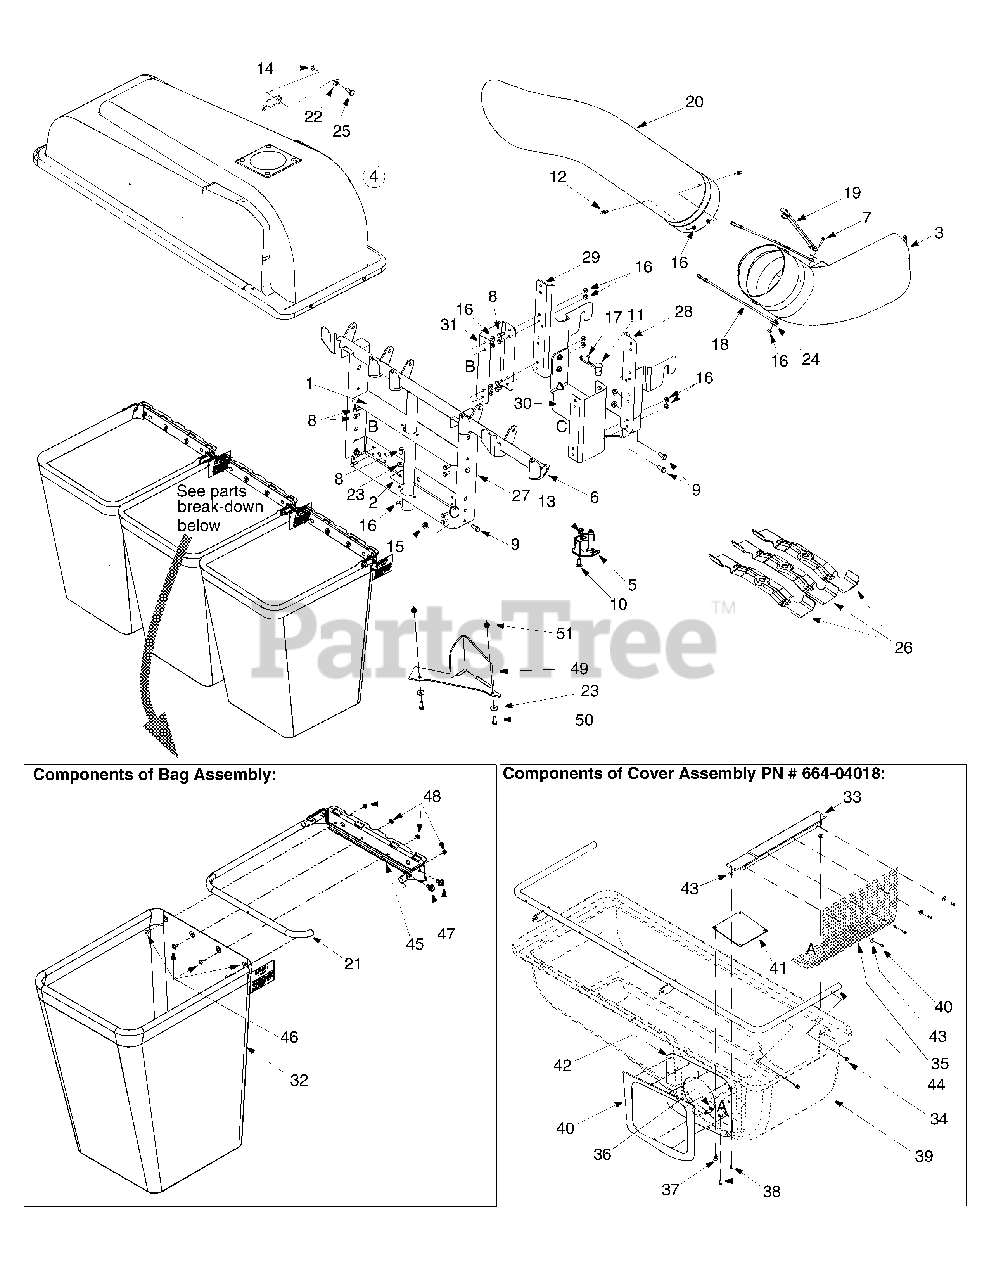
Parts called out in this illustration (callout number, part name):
3	Chute Elbow
4	Cover Assembly (includes ref. 35 to 46)
8	Hex Bolt 1/4-20 x 0.620
9	Hex Bolt 5/16-18 x 0.75
10	Carriage Bolt
11	Clevis Pin
12	Grass catcher Pin
13	Hex Lock Nut 3/8-16
14	Flange Lock Nut 3/8-16
15	Flange Lock Nut 5/16-18
16	Flange Lock Nut 1/4-20
17	Hairpin Clip
18	Chute Strap
19	Chute Strap
20	Catcher Tube
23	Bell Washer
24	Flat Washer
25	Shoulder Screw
26	Blade: High Lift;
35	Screen
36	Push Nut
37	Ratchet Clip
38	Pop Rivet
39	Grass Bag Cover
40	Retainer Seal
41	Plastic Plate
42	Grass Bag Seal
43	Flat Washer
46	Machine Screw
47	TT Screw 5/16-18 x 0.625
48	Hex Sems Nut
50	Hex Head Screw 1/4-20
51	Flange Lock Nut 1/4-20
